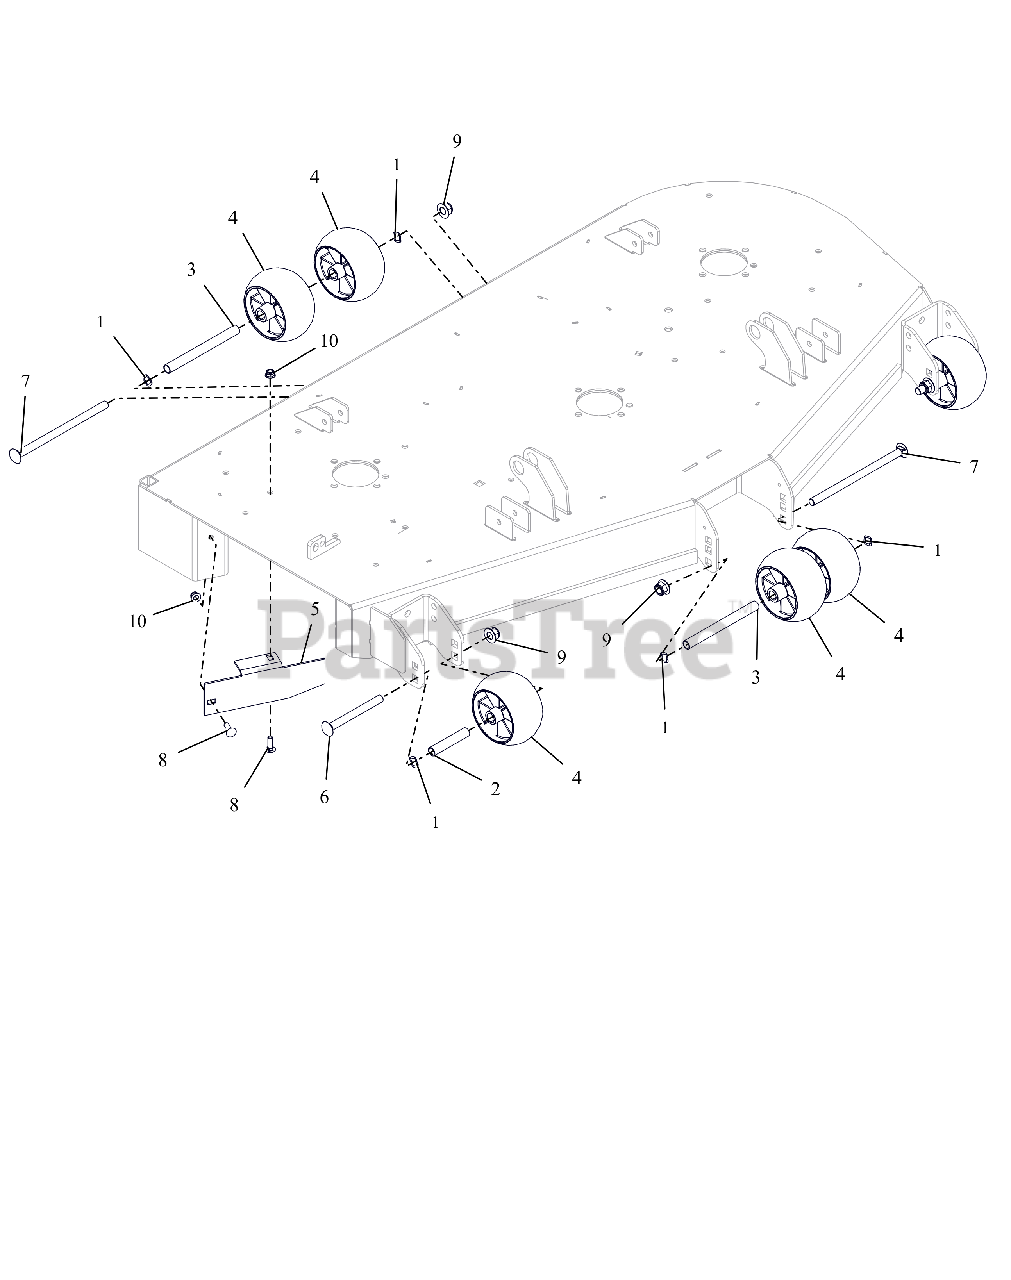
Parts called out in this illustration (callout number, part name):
1	WAVE WASHER .531X.781X.125FH
2	SPACER, .510X.625X3.35
3	SPACER, .510X.625X6.50
4	ANTI-SCALP WHEEL - 5X3 CTR
5	BAFFLE, DISCHARGE, 52"
6	BLT-RDHDSQNK .50-13X5.00 GR5YZ
7	@BLT-RDHDSQNK .50-13X8.50 G5YZ
8	@BLT-RDHDSQNK .31-18X1.00 G5YZ
9	@NUT-LK-NYL-FLG .50-13 YWZC
10	@NUT-LK-NYL-FLG .31-18 YWZC
